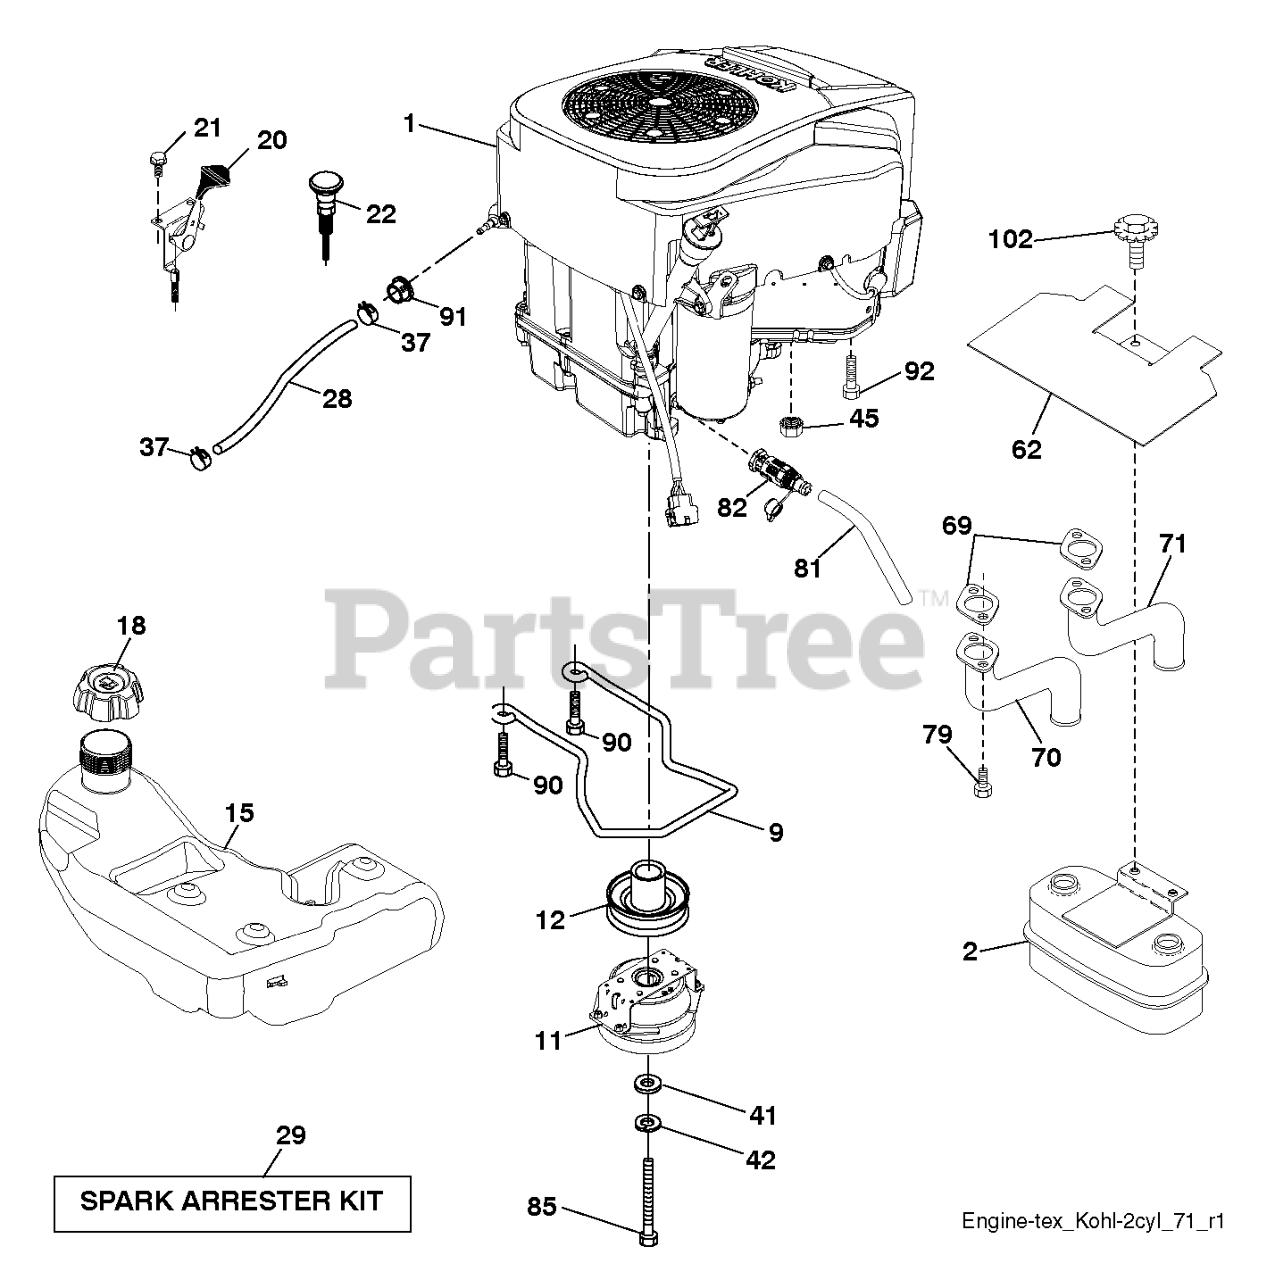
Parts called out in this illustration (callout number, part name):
2	MUFFLER.ASM.TWN.EXTNDED.DFLCTR
9	KEEPER BELT ENGINE
11	CLUTCH MZ ZTR GT.48/54"1.125"
12	PULLEY ENGINE
15	TANK.ASM.4.GAL.EPA.ONE.PORT
18	CAP.ASM.FL.RITCH.3"E10.SYM.498
20	THROTTLE CONTROL
21	SCREW.#10 X 0.750.BOS
22	CONTROL.CHOKE.ERGO.PUSH-IN.BLA
28	LINE.FUEL.64"REAR.EMIS
29	KIT.SPARK ARRESTOR 794945 B&S
37	HOSE CLAMP
42	LOCKWASHER
45	NUT
62	SHIELD.HEAT.MUFFLER
69	GASKET.EXHAUST.KOHL.CV18-CV26
70	RP.PIPE-EXHAUST LH
71	RP.PIPE-EXHAUST RH
79	SCREW.SOCKET HD.5/16-1
81	TUBE, DRAIN OIL ASM.
82	VALUE.OIL.DRAIN
85	BOLT HEX 7/16-20 X 3.75 GR. 5
87	BOLT.5/16-18UNCX3/4 W/SEMS.BLK
90	SCREW 3/8-16X1
92	SCREW 3/8-16X1
